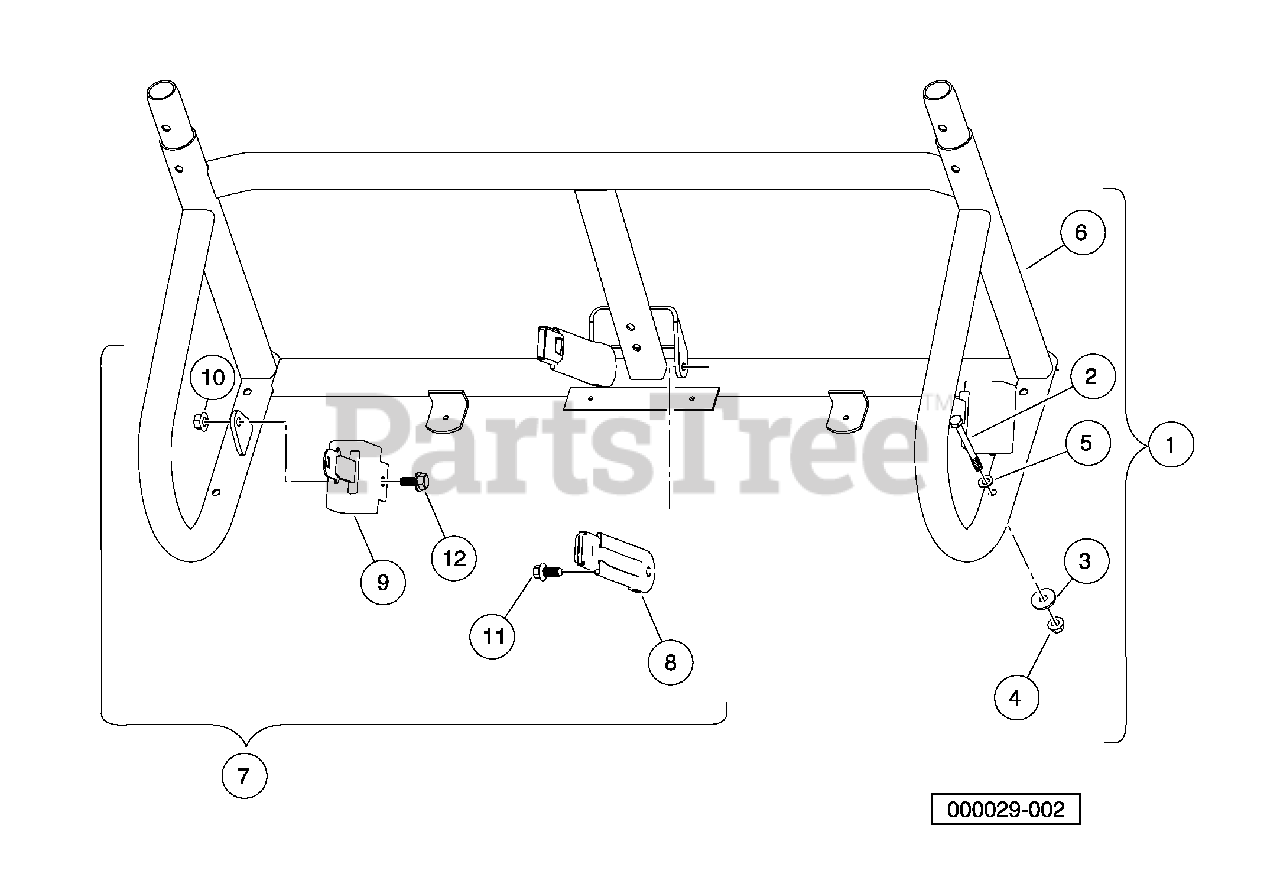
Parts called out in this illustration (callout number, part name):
1	Instl, Rops, Lower
2	BOLT, M10 X 100, ZN-NI/BLK
3	Washer Hard,m10
4	Nut Flg M10 X 1.5 Mech Def
5	Washer, Hard, M10, Zn-Ni/Blk
6	Weldment,seat Support,hs,rops
7	Instl, Seat Belt, Restyle
8	Buckle, Seat Belt with Sleeve.
9	Retractor, Seat Belt
10	Ln Flg, M12 X 1.75, Md, Black
11	Screw,m12x1.75x30 Thd Form Blk
12	Bolt Flg, M12x1.75 X 25 Black
